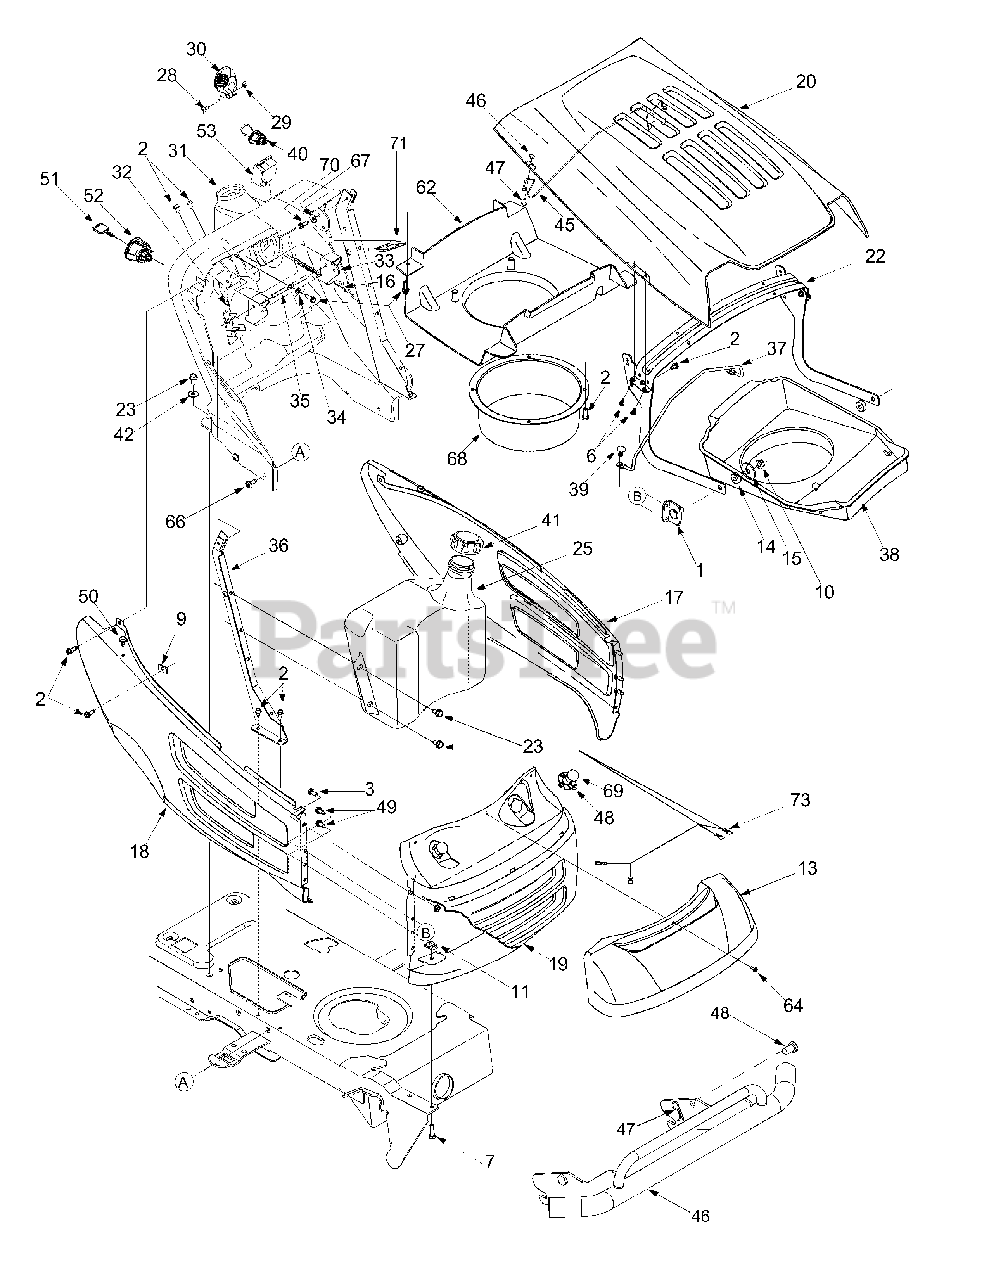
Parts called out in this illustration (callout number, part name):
2	Self-tapping Screw, 1/4-20 x .5
3	Hex Cap Screw, 1/4-20 x .62
4	Phillips Pan Screw, 1/4-20 x .75
6	Screw, #10-16 x .5
7	Hex Cap Screw, 5/16-18 x 1.0
8	Hex Sems Nut, 1/4-20
9	U-type Speed Nut, 1/4-20
10	Flange Lock Nut, 3/8-16
11	U-nut, 5/16-18
13	Headlight Lens
14	Rubber Washer, .87 x .33
15	Flat Washer, .406 x 1.5 x 11GA
16	Choke Knob/Cable (B&S Twin)
21	Hood Hinge Bracket
22	Hood Support Bracket
23	Self-tapping Screw, 5/16-18 x .625
24	Fuel Tank, Three Gallon
24	Fuel Tank, Two Gallon (shown)
25	Fuel Cap (fits either tank)
26	Self-tapping Screw, 1/4-20 x 1.25
27	Self-tapping Screw, 1/4-15 x .75
28	Truss Phillips Screw, #8-32 x .375
29	Hex Nut, #8-32
30	Throttle Control Knob
31	Dash Panel (Models w/ Electric PTO)
31	Dash Panel (Models w/ Manual PTO)
32	Cruise Control Button
32	Cruise Cover (Models w/o Cruise)
33	Parking Brake Button
34	Flat Washer, 9/32 x 1/2 x 1/16
35	Brake/Cruise Pivot Rod
36	Dash Support Tube
37	Hood Plenum Support Rod
38	Hood Plenum (B&S OHV V-Twin)
38	Hood Plenum (B&S Opposed Twin)
39	Ratchet Clip
40	Electric PTO Switch (if equipped)
41	Hex Flange Lock Nut, 1/4-20
42	Flat Washer, .349 x 1.0 x .063
45	Hood Latch
46	Hex Sems Nut, #10-32
47	Machine Screw, #10-24
48	Headlight Socket
49	Hex Index Washer Scr., 1/4-14 x .0625
50	Rubber Bumper
51	Ignition Key
52	Ignition Switch
53	Systems Ind. Monitor w/ Hour Meter
53	Systems Ind. Monitor w/ Ammeter
58	Clevis Pin, .50 x .78
59	Bumper Assembly
60	Internal Cotter Pin
61	Hood, Red
61	Hood, Green
61	Hood, Black
61	Hood, Charcoal Grey
62	Hood Plenum
63	Hood Bracket
64	Hex Screw, #10 x .50
65	Choke Plug
66	Screw, 5/16-18 x .75
67	Bell Washer, .265 x .75 x .062
68	Intake Bellow (Intek Single & kohler)
70	Self-tapping Screw, 1/4-20 x .75
71	Bracket: Elec. PTO Switch (if equipped)
72	Headlight Wire Harness
72	Tractor Wire Harness
